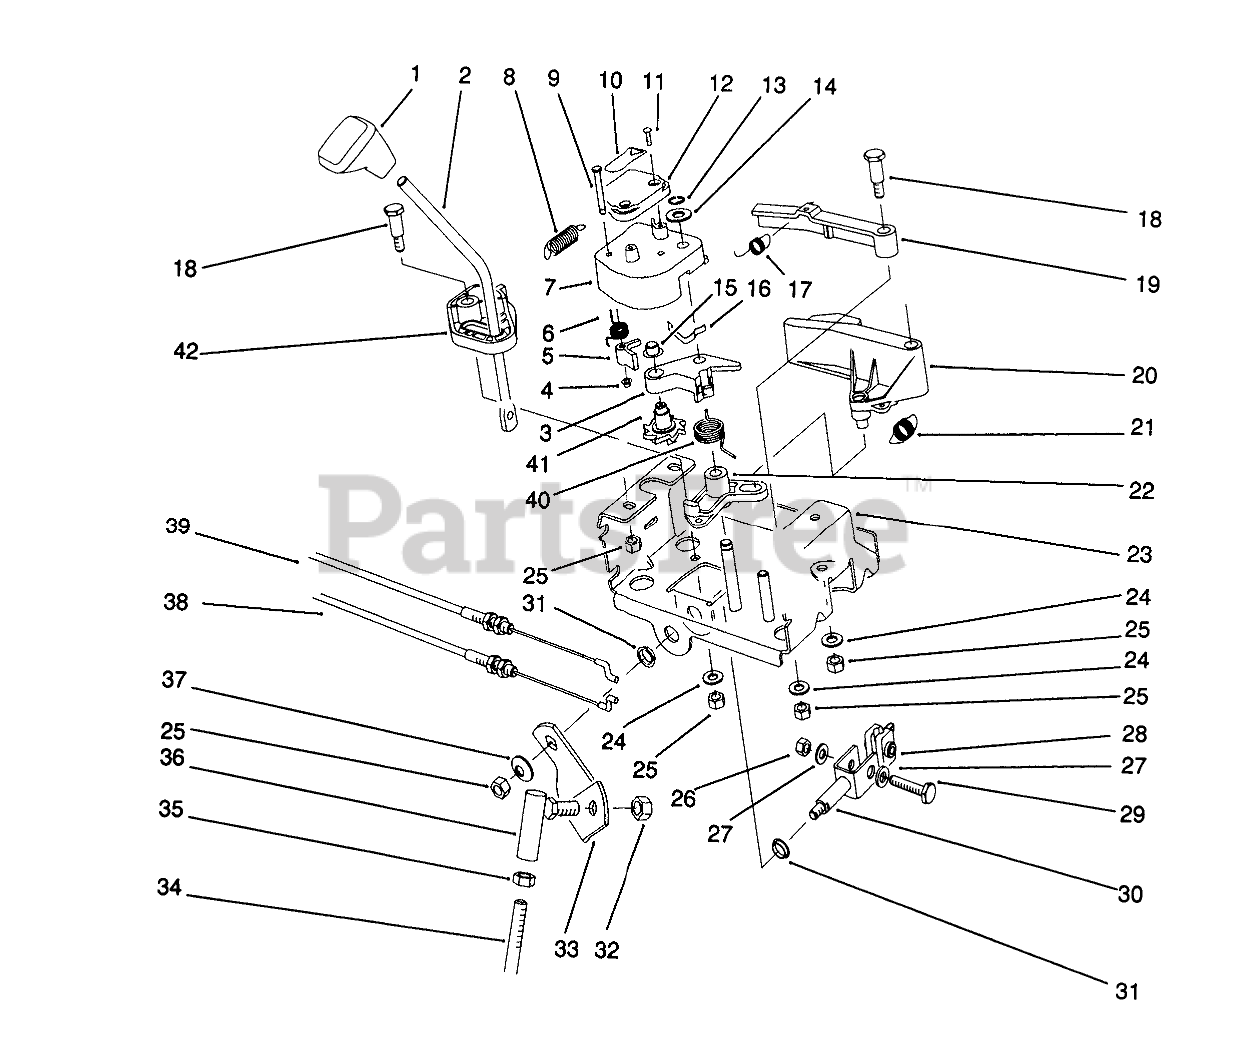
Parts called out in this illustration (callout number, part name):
1	KNOB-SHIFT
2	ROD-SHIFT
3	LEVER-WHEEL, INDEX
4	NUT-PUSH
5	TANG-INDEX
6	SPRING-TORSION
7	LATCH-LEVER
8	SPRING-EXTENSION
9	PIN-TANG
10	DECAL
11	SCREW-PPH
12	COVER-LATCH
13	RING-RETAINING
14	WASHER-THRUST
15	RETAINER-PUSH ON
16	SPRING-FLAT
17	SPRING-EXTENSION
18	SCREW-SHOULDER
19	LEVER-LOCKOUT
20	LEVER-REVERSE
21	SPRING-EXTENSION
22	LEVER-REVERSE, SWITCH
23	Frame-Control
24	WASHER-PLAIN
25	NUT-LOCK, NI
26	NUT-LOCK, NI
27	WASHER-FLAT
28	RETAINER-ROD, SHIFT
29	SCREW-HH
30	CLEVIS ASM
31	BUSHING
32	NUT-LOCK, NI
33	BRACKET-SHIFT
34	ROD-BENT SHIFT, LOWER
35	NUT-HJ
36	JOINT-BALL
37	WASHER-BELLEVILLE
38	CABLE-GEARBOX
39	CABLE-ARM, LATCH
40	SPRING-TORSION
41	WHEEL-INDEX
42	BASE-LOCKOUT
